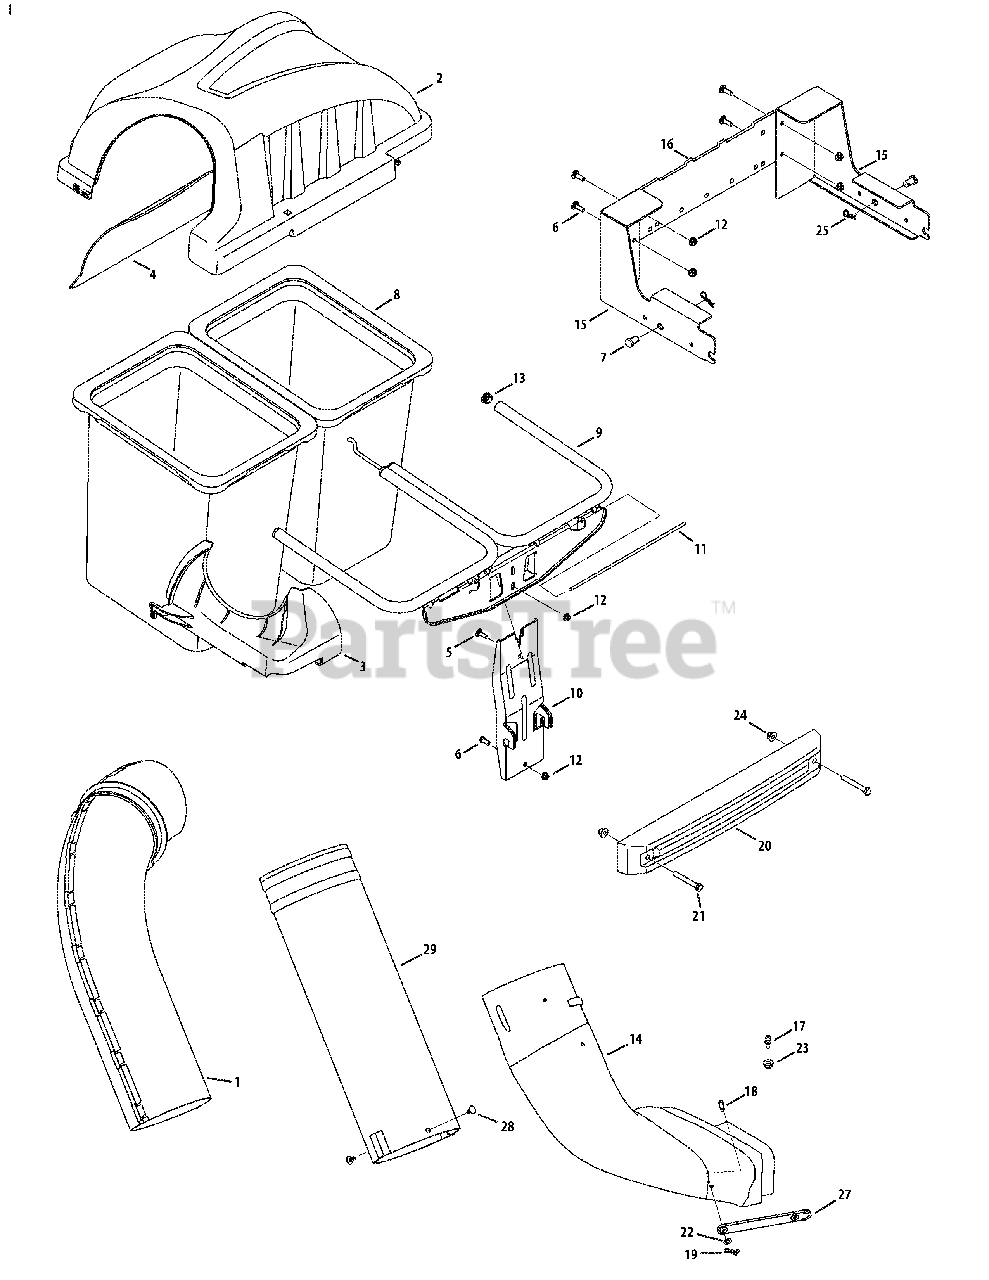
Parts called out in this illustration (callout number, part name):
1	Upper Chute Assembly
2	Twin Bagger Cover Assembly
3	Upper Chute Support
4	Bagger Cover Screen
5	Carriage Screw, 5/16-18 x 1.00"
6	Hex Head Screw, 5/16-18 x .75"
7	Clevis Pin, .50" Dia.
8	Grass-bag Assembly
9	Twin Bag Support Assembly
11	Cover Hinge Pin
12	Flange Lock Nut, 5/16-18
14	Discharge Chute Elbow
15	RZT Hitch Bracket Kit (RH & LH)
16	Universal Cross Bracket
17	Grass-catcher Pin
18	Clevis Pin 5/16 x 3/4
19	Bow-Tie Cotter Pin
20	Bagger Weight
21	Hex Head Screw, 3/8 - 16 x 2.75
22	Flat Washer, .344 x .62 x .033
23	Flange Lock Nut, 1/4 - 20
24	Flange Lock Nut, 3/8 - 16
25	Cotter Pin, .080 x 1.5625 Internal
26	RZT Bagger Weight
27	Chute Strap
28	Ratchet Clip, .250
29	Bagger Chute Adapter, 7 In.
